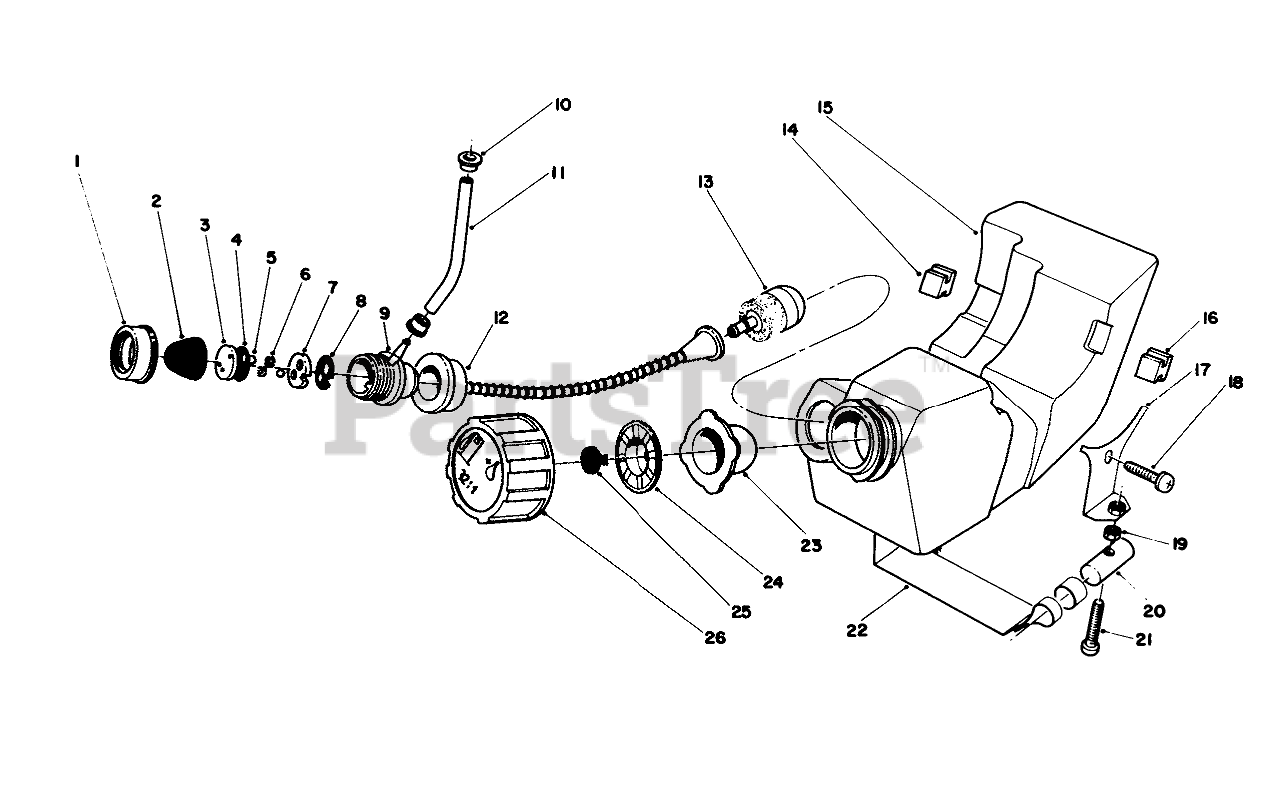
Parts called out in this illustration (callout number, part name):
1	PUMP CAP
3	SEAT VALVE
4	GASKET
6	SPONGE
7	SEAT VALVE
8	GASKET
9	Primer Pump Assembly (Incl. Ref. #1-8)
11	TUBE, FUEL
12	SUCTION HOSE
13	FUEL FILTER
15	Fuel Tank Assembly (Incl. Ref. #1-9, 12, 13, 23-26)
17	Hanger-Tank
18	Screw
21	Screw
22	BAND, TANK
23	GASKET - PACKING
24	HOLDER
25	BREATHER VALVE
26	TANK CAP
